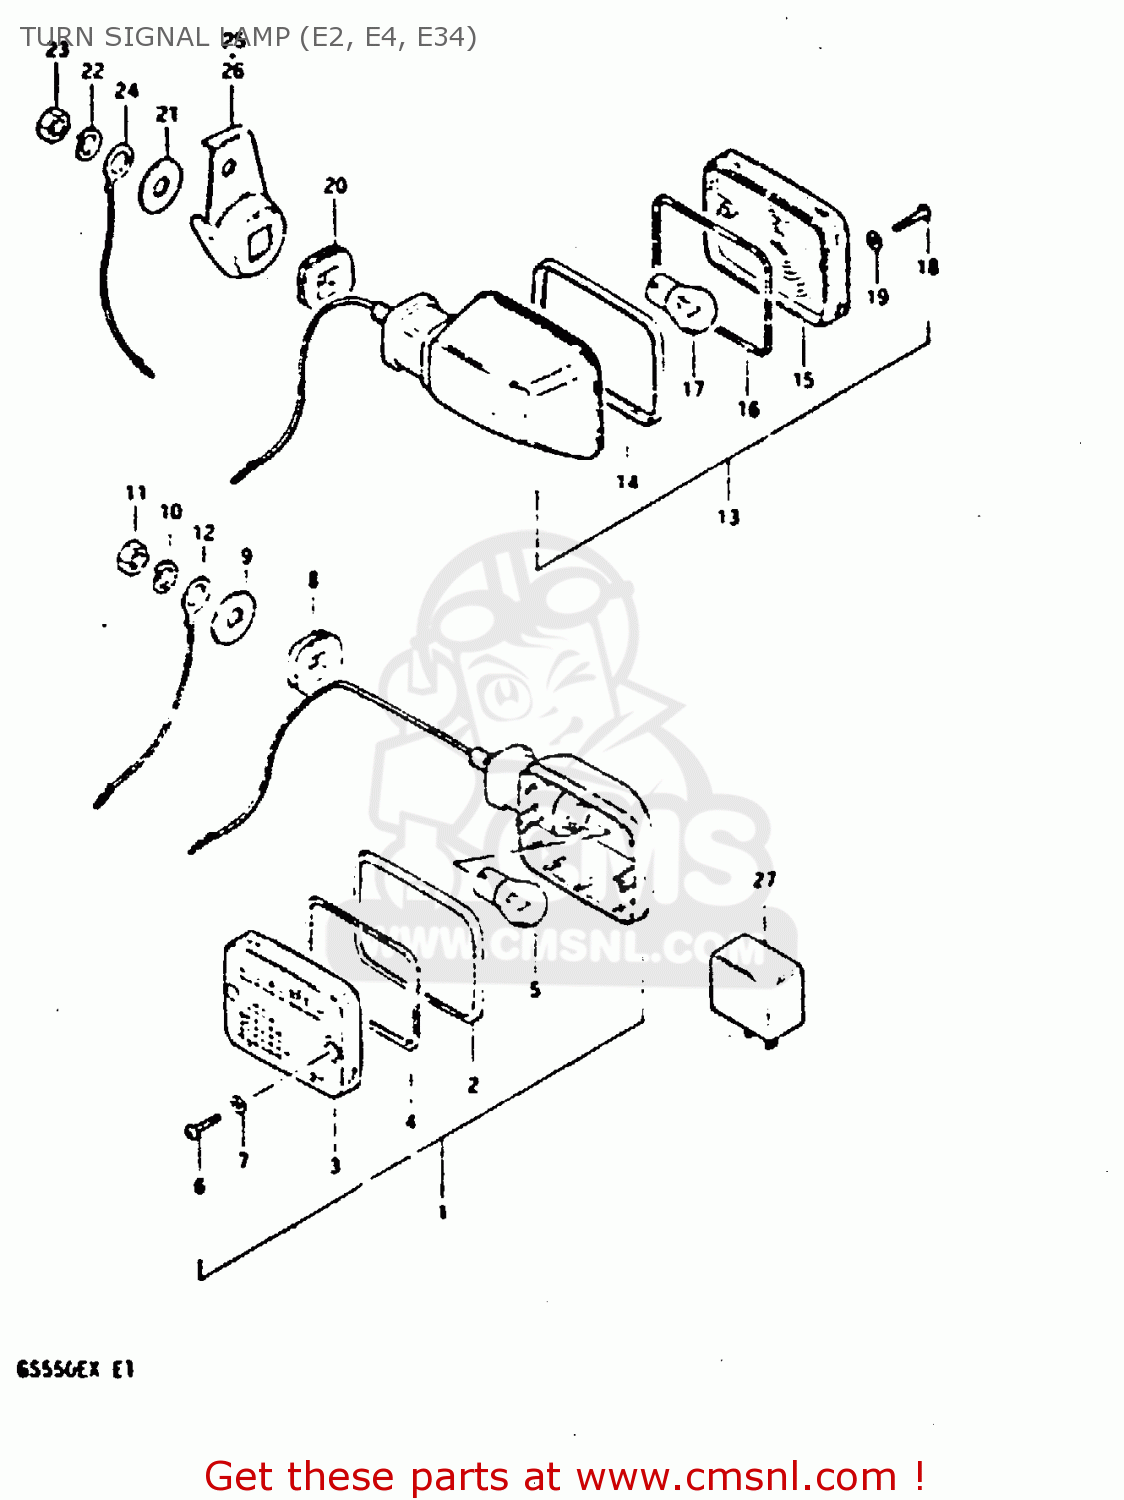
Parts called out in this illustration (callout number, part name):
1	LAMP ASSEMBLY,FRONT TURN SIGNAL
2	RIM
3	LENS
4	GASKET (NAS)
5	BULB 12V 21W
6	SCREW
7	GASKET (NAS)
8	CUSHION
9	WASHER (10.5X30X2.3)
10	LOCK WASHER
11	NUT
12	WIRE
13	LAMP, REAR TURN SIGNAL
14	RIM
15	LENS
16	GASKET (NAS)
17	BULB 12V 21W
18	SCREW
19	GASKET (NAS)
20	CUSHION
21	WASHER (10.5X30X2.3)
22	LOCK WASHER
23	NUT
24	WIRE
25	BRACKET,REAR TURN SIGNAL
26	BRACKET,REAR TURN SIGNAL
27	RELAY,TURN SIGNAL
